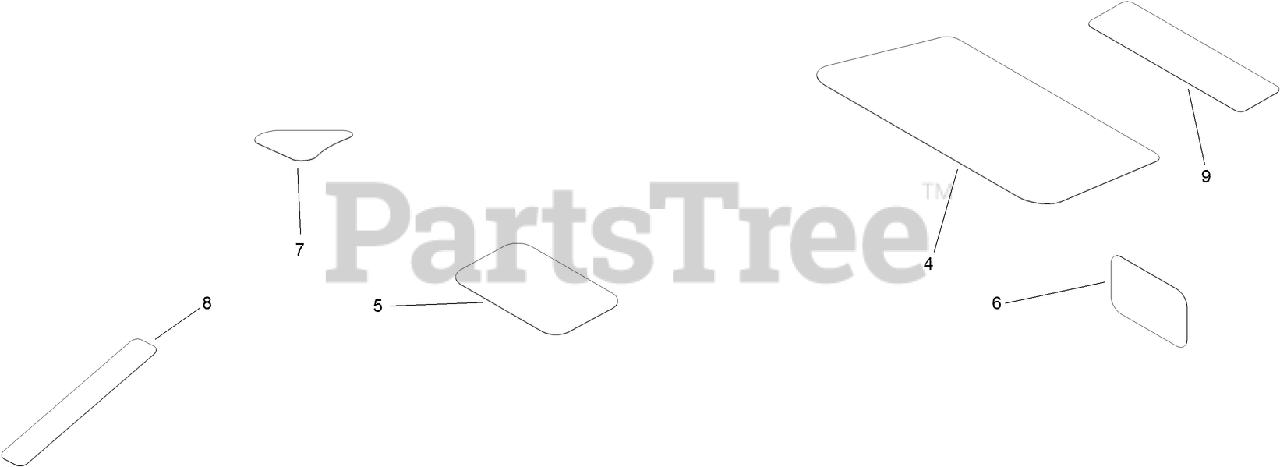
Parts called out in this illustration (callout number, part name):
4	DECAL-ENGINE
6	PLACARD-INTAKE
7	DECAL-DRAIN, OIL
8	DECAL-SHUTDOWN
9	DECAL-BUCKET
